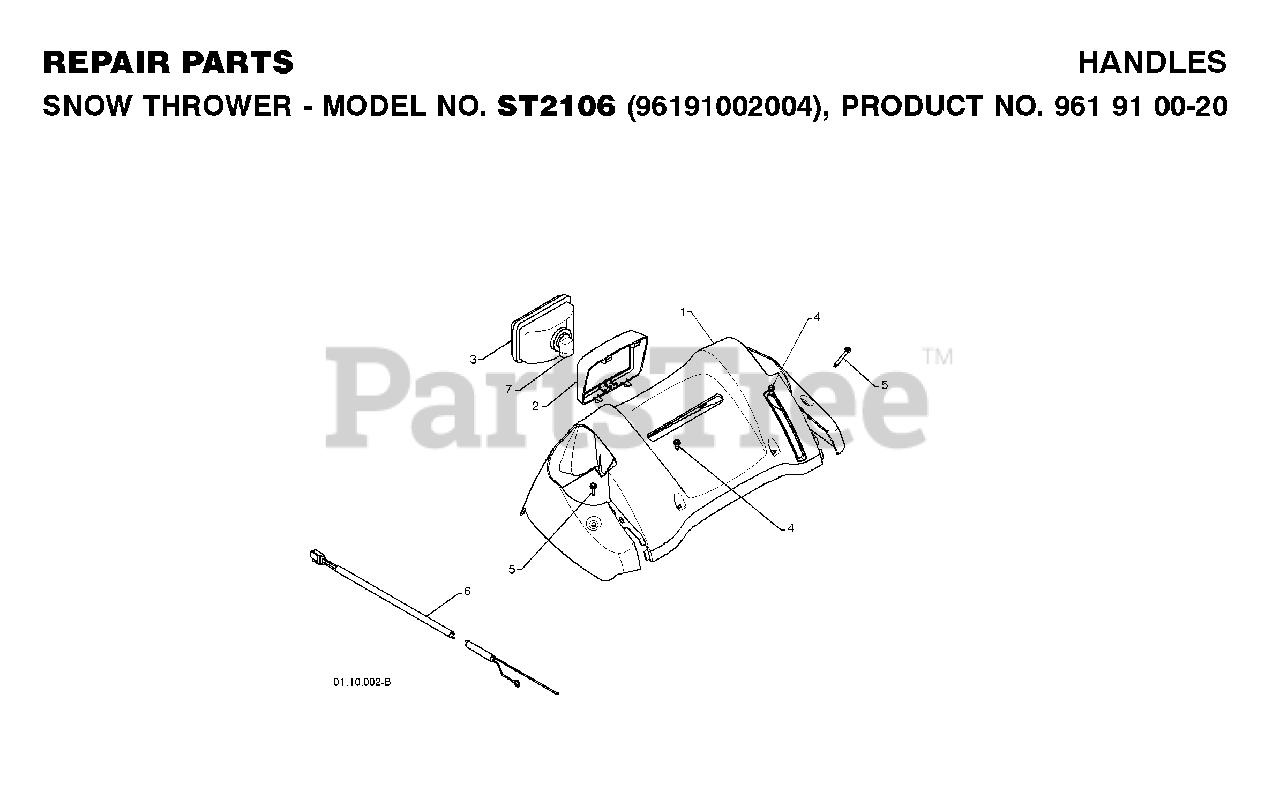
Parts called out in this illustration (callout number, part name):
1	PANEL.CONSOLE.HEADLIGHTS
2	BEZEL.HEADLIGHT.BLACK
3	HEADLIGHT, HALOGEN
4	SCREW, HEX HEAD, TAPPING
5	SCREW, HEX HD TAPPING #10-24 1
6	HARNESS.WIRE.HALOGEN
7	BULB.HEADLIGHT.HALOGEN.
